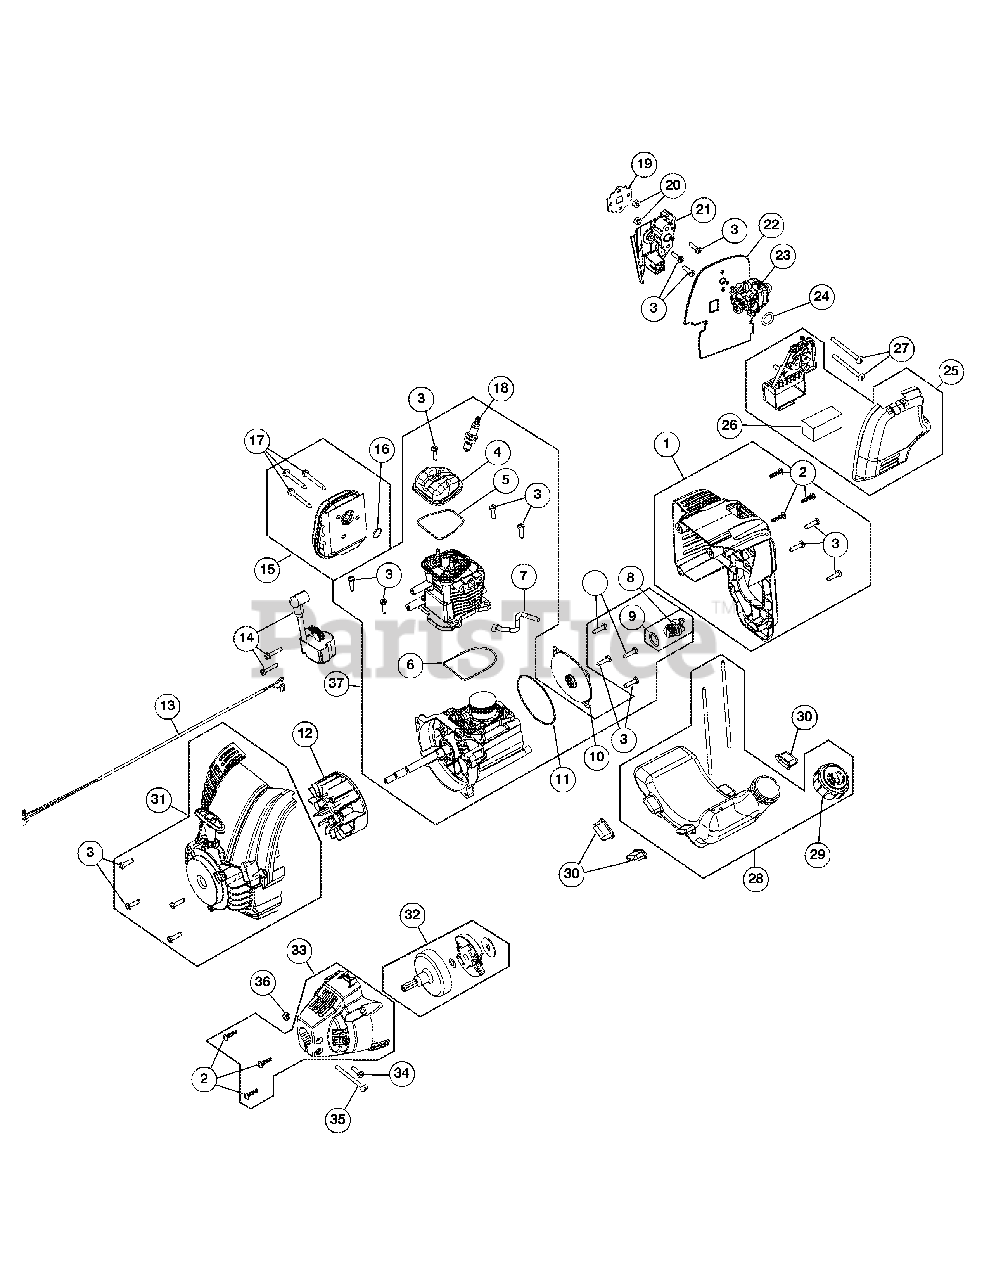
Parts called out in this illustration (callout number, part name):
1	Engine Cover Assembly (Incl. Ref No. 2 & 3)
2	Cover Screw
3	Screw
4	Rocker Cover
5	Rocker Cover O-Ring
6	Cylinder O-Ring
7	Breather Hose
8	Oil Plug (Incl. Ref No. 9)
9	Oil Plug O-Ring
10	Crankcase Cover
11	Crankcase Cover O-ring
12	Flywheel Assembly
13	Lead Wires
14	Module Assembly
15	Muffler Assembly (Incl. Ref No. 16 & 17)
16	Muffler Gasket
17	Muffler Screw
18	Spark Plug
19	Insulator Gasket
20	Nut
21	Insulator
22	Carburetor Gasket
23	Carburetor w/Primer
24	Air Cleaner O-Ring
25	Air Cleaner Cover Assembly (Incl. Ref No. 32)
26	Air Filter
28	Fuel Tank Assembly w/Fuel Lines (Incl. Ref No. 35)
29	Fuel Cap
30	Fuel Tank Pads
31	Starter Housing Assembly (Incl. Ref No. 3 & 37-45)
32	Clutch Assembly
33	Clutch Cover (Incl. Ref No. 2)
34	Anti-Rotation Screw
35	Clamp Screw
36	Nut
37	Shortblock Assembly
